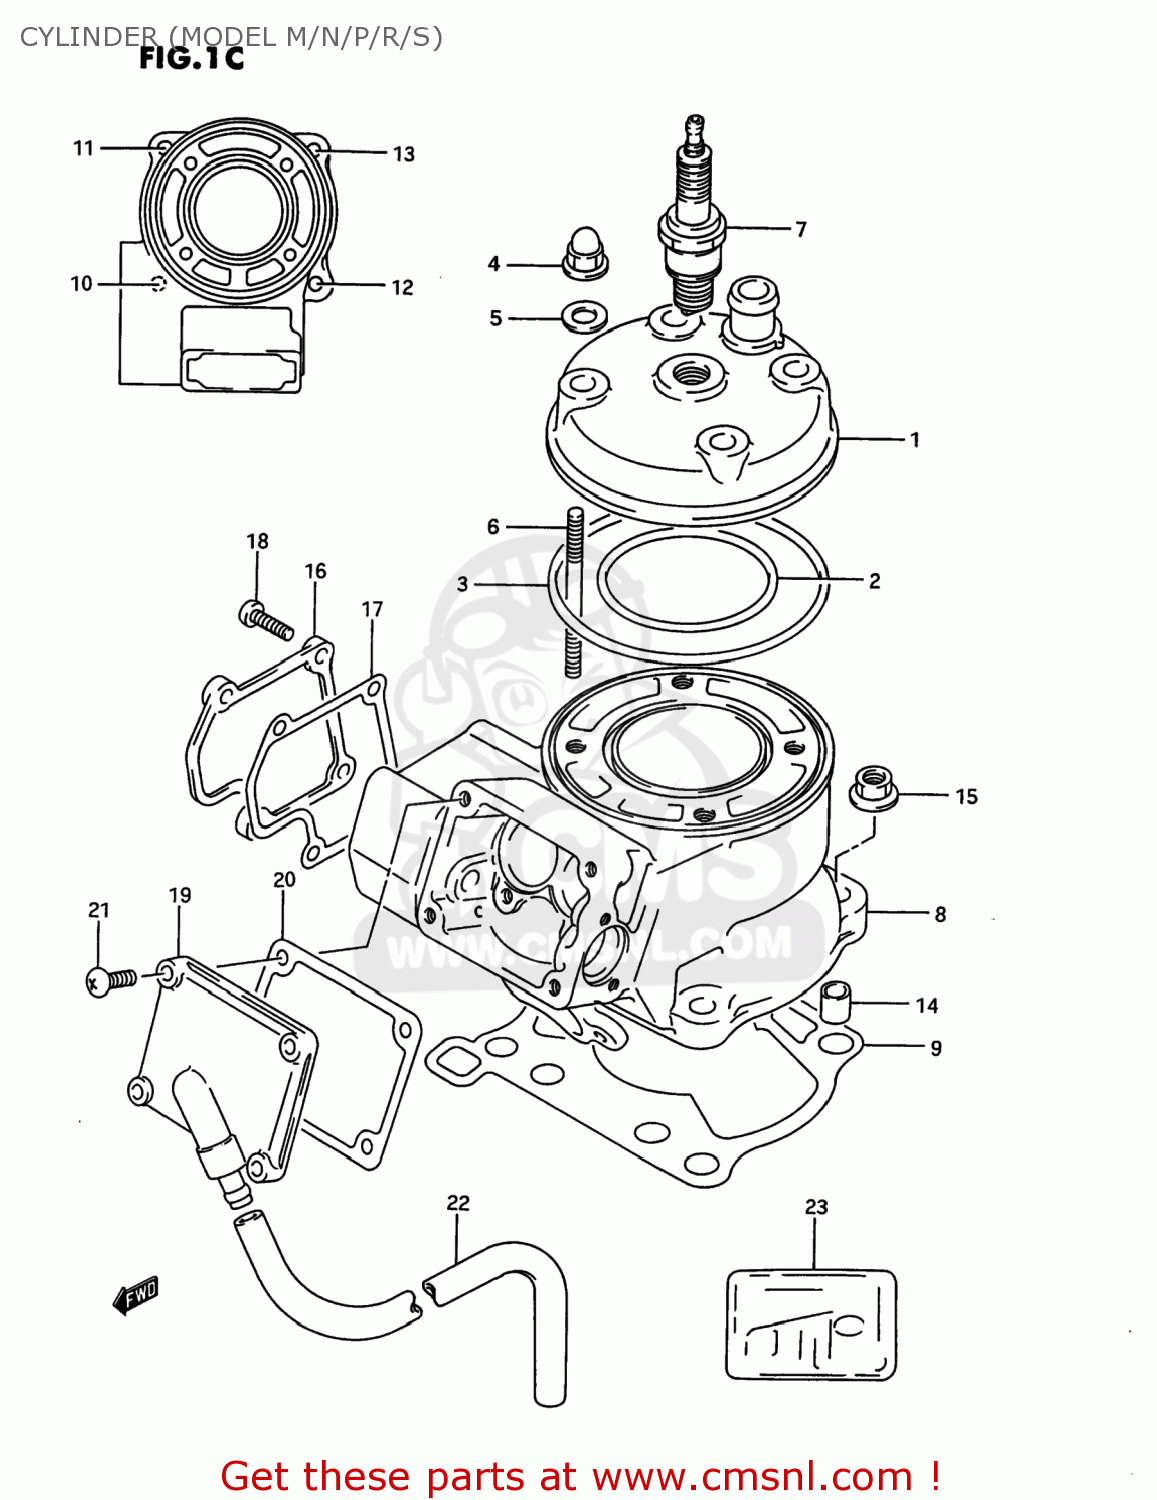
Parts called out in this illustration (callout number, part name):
1	HEAD,CYLINDER
2	O RING,CYLINDER HEAD NO.1
3	O RING,CYLINDER HEAD NO.2
4	NUT
5	GASKET(8.5X17X2.3) (NAS)
6	BOLT,STUD
7	SPARK PLUG B10ES
8	CYLINDER COMP
9	GASKET,CYLINDER (NAS)
10	BOLT,STUD
11	STUD 8X25
12	BOLT,STUD
13	BOLT,STUD
14	PIN(8.4X11X14)
15	NUT
16	COVER,CYLINDER NO.1
17	GASKET,CYLINDER COVER NO.1 (NAS)
18	BOLT
19	COVER,CYLINDER
20	GASKET,CYL COVER NO.2 (NAS)
21	BOLT
22	HOSE (6.5X11.5X300)
23	GASKET SET (NAS)
